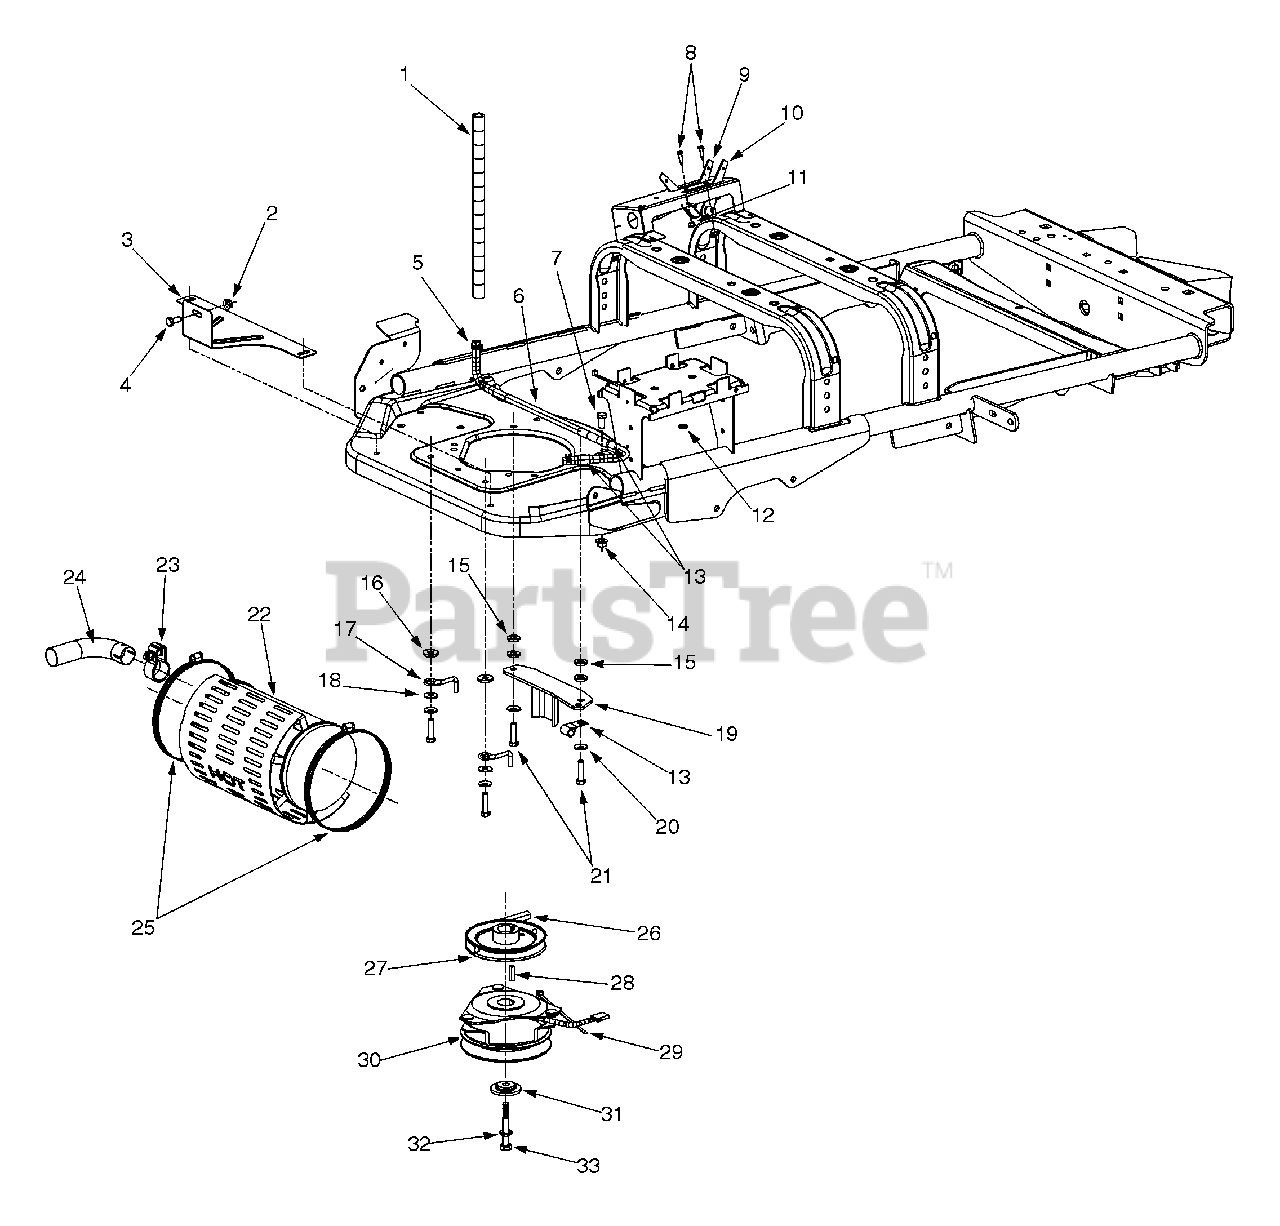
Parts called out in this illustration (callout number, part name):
1	Oil Drain Hose
2	Flange Lock Nut 5/16-18
3	Mounting Muffler Bracket
4	Hex Cap Screw 5/16-18 x .75
5	Hose Clamp
6	Fuel Line Hose
7	Hex Cap Screw 3/8-16 x .75
8	Screw #10-24 x .750
9	Throttle Control Cable 53.0"
10	Choke Control Cable 43.0"
11	Nylon Lock Nut #10-24
12	Lock Washer 5/16
13	Heat Shield Cable Clip
14	Flange Lock Nut 3/8-16
15	Flat Washer .407 ID x .812 OD
16	Flat Washer .385 ID x 1.0 OD
17	Rear Belt Retainer Rod
18	Washer 5/16
21	Hex Cap Screw
24	Muffler Tube
25	Adjustable Clamp
26	V-Belt
28	Key 1/4 x 1.0
29	Cable Tie
30	Electric PTO Clutch
31	Spacer Clutch
32	Lock Washer 7/16
33	Hex Cap Screw
